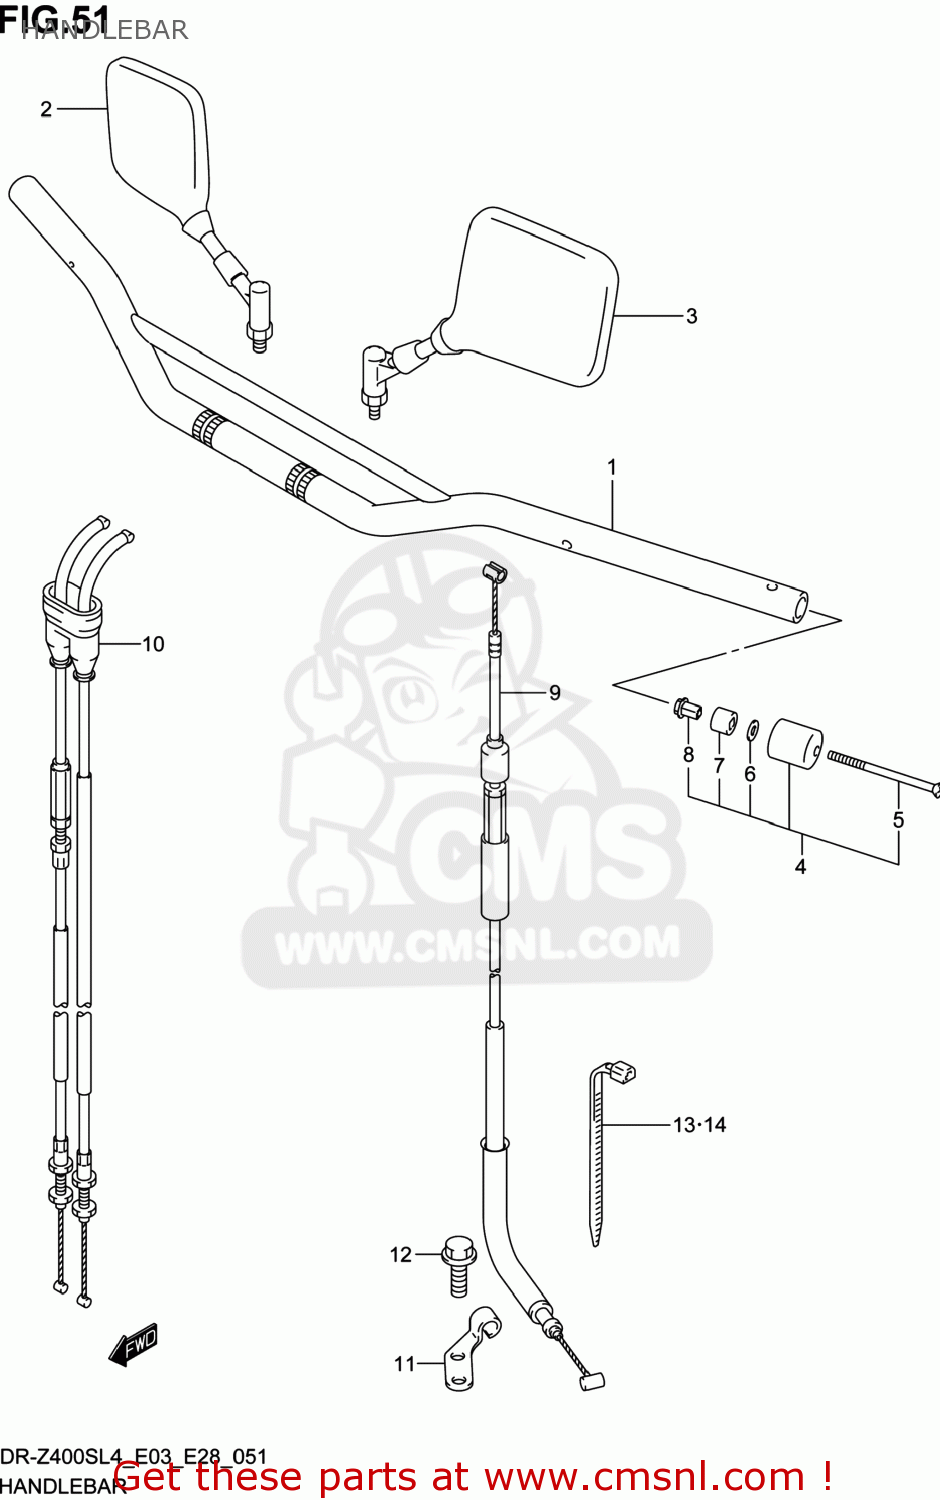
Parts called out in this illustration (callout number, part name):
1	HANDLEBAR(SILVER)
2	MIRROR ASSY,RR VIEW,R
3	MIRROR ASSY,RR VIEW,L
4	BALANCER SET,HANDLEBAR
5	SCREW
6	WASHER(6.5X16X4)
7	EXPANDER,HANDLE BALANCER
8	NUT,HANDLE BALANCER
9	CABLE ASSY,CLUTCH
10	CABLE SET,THROTTLE
11	STOPPER,CLUTCH CABLE
12	BOLT
13	CLAMP(L:100)
14	CLAMP(L:235)
